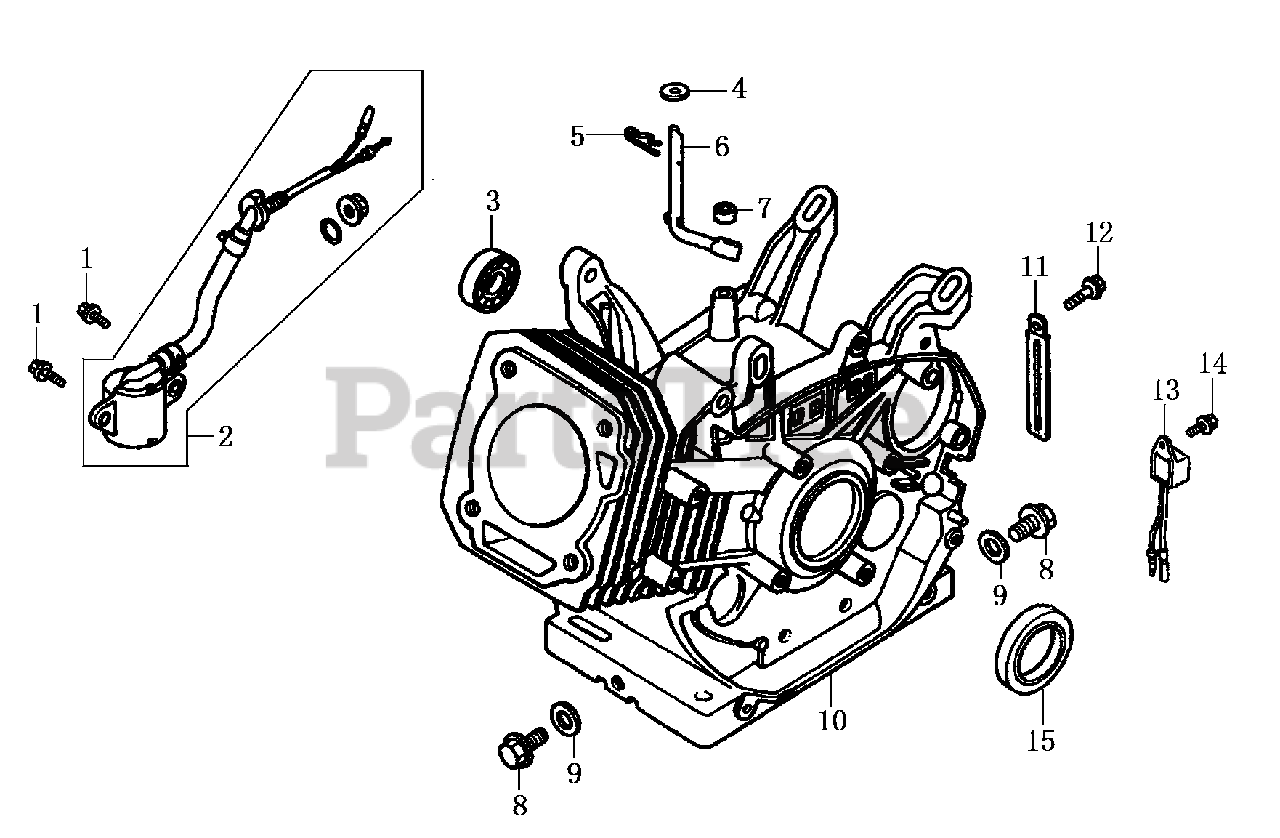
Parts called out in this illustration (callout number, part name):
1	BOLT, FLANGE
2	SWITCH ASSY., OIL LEVEL
3	BEARING, RADIAL BALL 6202
4	WASHER, FLAT 8*16*1.2
5	PIN, LOCK, 10MM
6	SHAFT, GOVERNOR ARM
7	SEAL, OIL
8	BOLT, DRAIN PLUG
9	WASHER, DRAIN PLUG, 12MM
10	CRANKCASE, (ELECTRIC START)
11	CLEAT, CABLE
12	BOLT, FLANGE, 6X12
13	ALERT UNIT,OIL
14	BOLT, FLANGE, 6X12
15	SEAL, OIL
